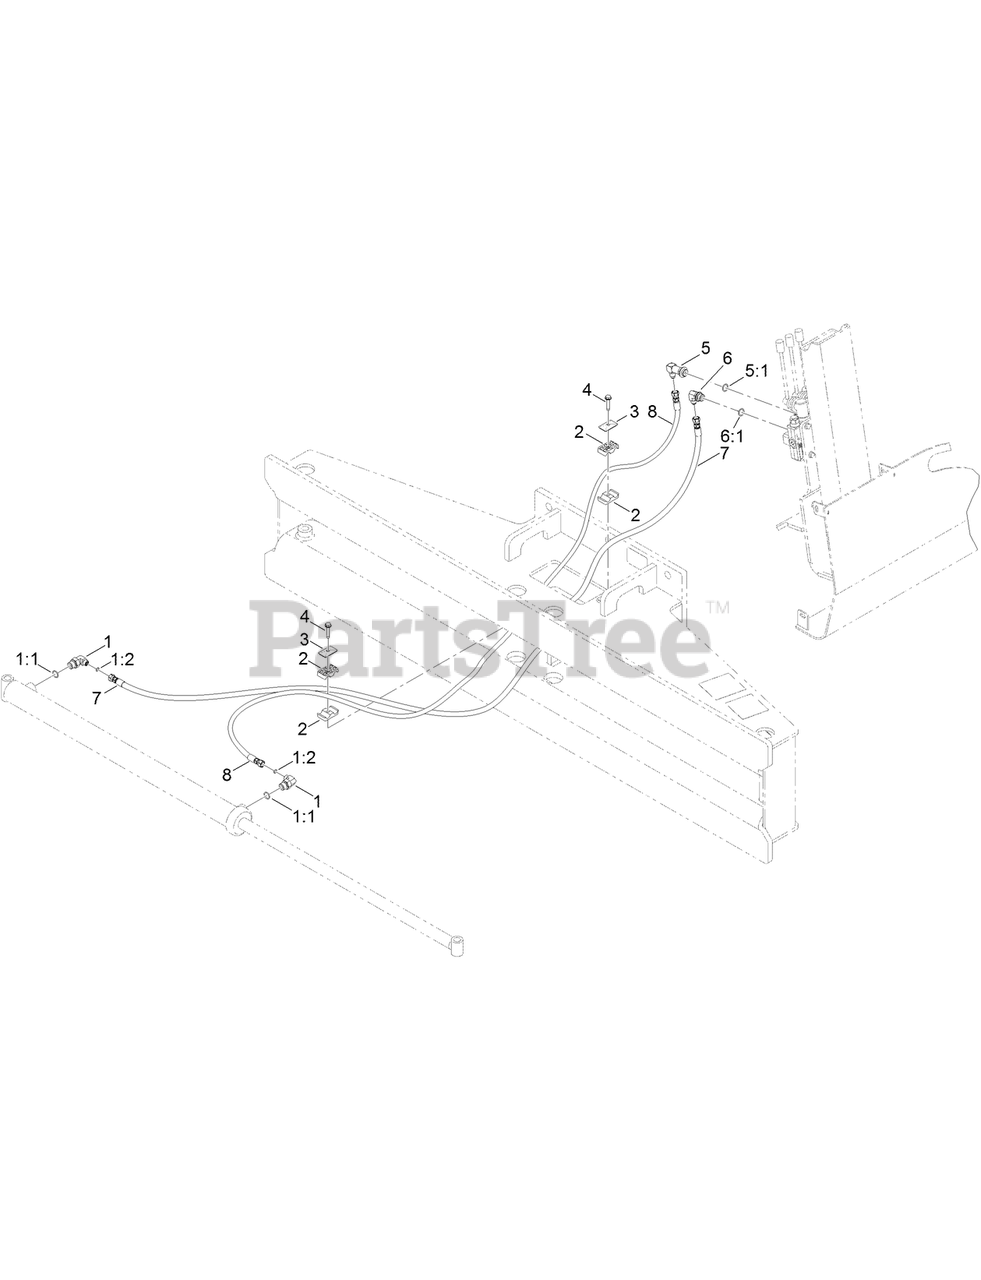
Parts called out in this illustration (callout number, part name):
1	FITTING-ELBOW 90
1:1	O-RING
1:2	O-RING
2	CLAMP-TUBE
3	COVERPLATE
5	FITTING-HYD
5:1	O-RING
6	FITTING-ELBOW, 90 DEG
6:1	O-RING
7	HOSE-HYDHP
8	HOSE-HYDHP
